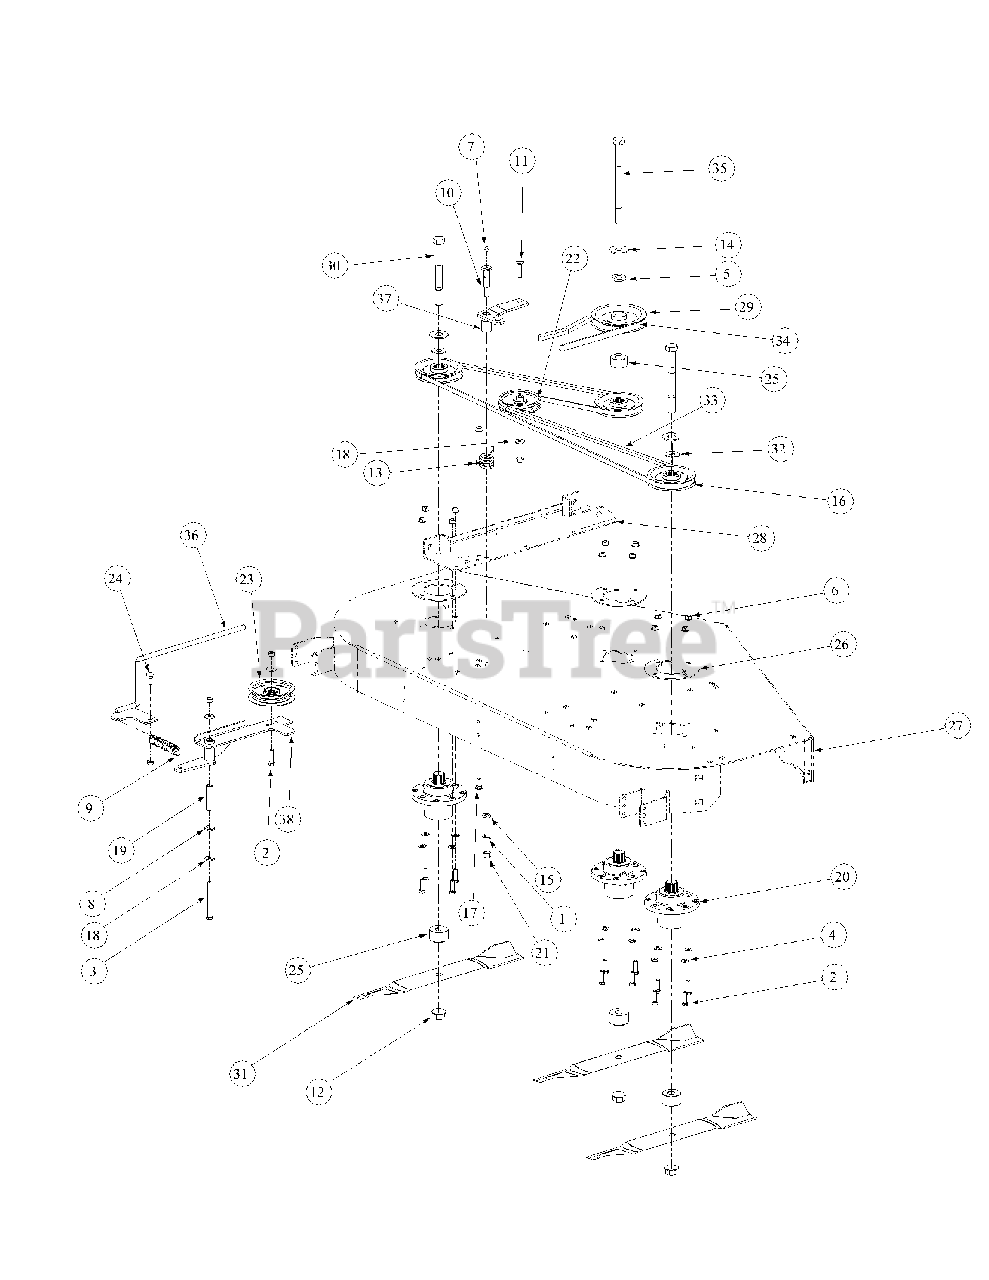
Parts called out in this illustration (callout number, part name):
1	Lock Washer, 7/16
2	Hex Cap Screw, 3/8-16 x 1-1/2
3	Hex Cap Screw, 3/8-16, 3.75
4	Flat Washer, 3/8
5	Caster Spacer
6	Flange Lock Hex Nut, 3/8-16
7	Grease Fitting, 1/4-28 x 3/16
8	Idler Washer
9	Extension Spring, 1.0 x OD x 5.125
10	Shoulder Screw, 7/16-14
11	Hex Carriage Screw, 3/8-16, 1.75
12	Flange Hex Nut, 3/4-16
13	Torsion Idler Spring
14	Flat Washer, .781 ID 2.00 OD, .105
15	Flat Washer, .469 ID, .875 OD, .105
16	V-Pulley, 4.65 OD
17	Carriage Bolt, 3/8-16 x 1
18	Flat Washer, .406 ID, 1.0 OD, .105
19	Spacer, .39 ID x .625 OD x 2.75
20	Aluminum Spindle Assembly
21	Hex Nut, 7/16-14
22	Flat Pulley
23	Idler Pulley, 4.06 OD
24	Shoulder Screw, .50 x .27 Lg., 3/8-16
25	Spacer, .760 ID x 2.00 OD x 1.1
26	Aluminum Spindle Support Plate
27	60 Deck Assembly
28	Left Hand Mount Deck Bracket Assembly
29	V-Pulley, 5.774 OD
30	Hex Cap Screw, 3/4-16, 7.00
31	Hi-Lift Blade, 21.0, 0.756 ID
32	Spacer .812 ID x .268 LG
33	V-Belt, A Section x 122.3
34	V-Belt, B Section x 91.2
35	Hex Cap Screw, 3/4-16, 9.00
36	Spring Tension Rod Assembly
37	Idler Arm Assembly, Deck Spindle
37	Bearing Sleeve
38	Idler Arm Assembly, Flat Top Bearing
38	Bearing Sleeve
